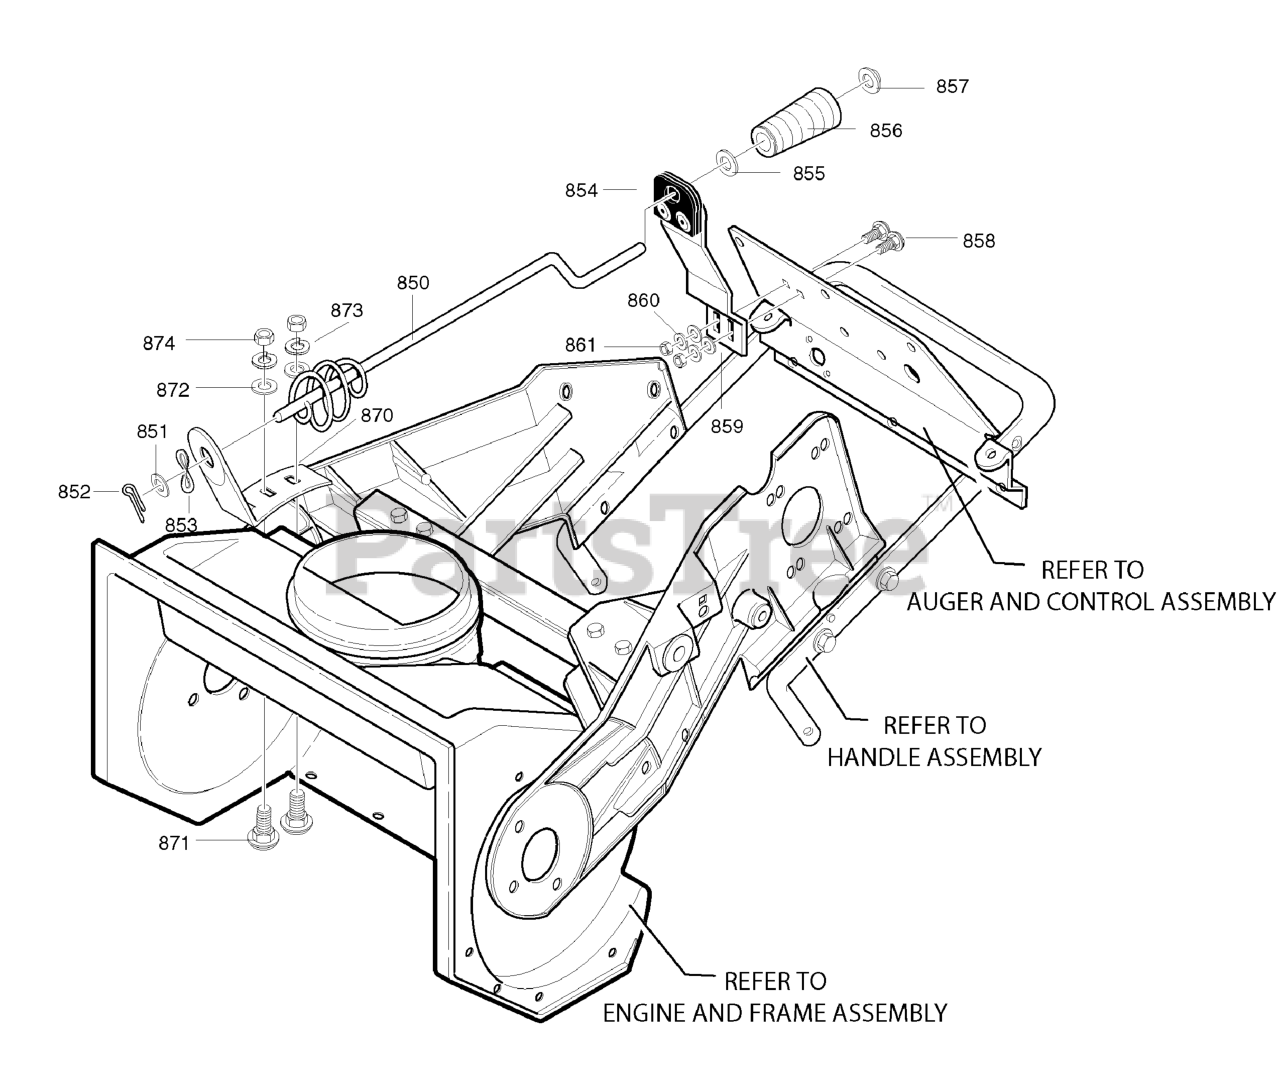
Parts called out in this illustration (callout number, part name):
850	ROD, CHUTE
851	WASHER, Flat, 13/32
852	PIN, COTTER
853	WASHER CURVED
854	ASSY, CHUTE CRANK
855	WASHER, Flat, 13/32
856	KNOB, SLEEVE
857	NUT, PUSH
858	BOLT,1/4-20 X .63 CARRIAGE
859	WASHER, FLAT .349 X .69 X .065
860	WASHER, .31 X .58 X .08
861	NUT, 1/4-20 HEX
870	BRKT, CHUTE ROTATE
871	BOLT, 5/16-18 X .75 CARRIAGE
872	WASHER, FLAT .349 X .69 X .066
873	WASHER, SPLIT LOCK .31 X .58 X .08
874	NUT, 5/16-18 HEX
